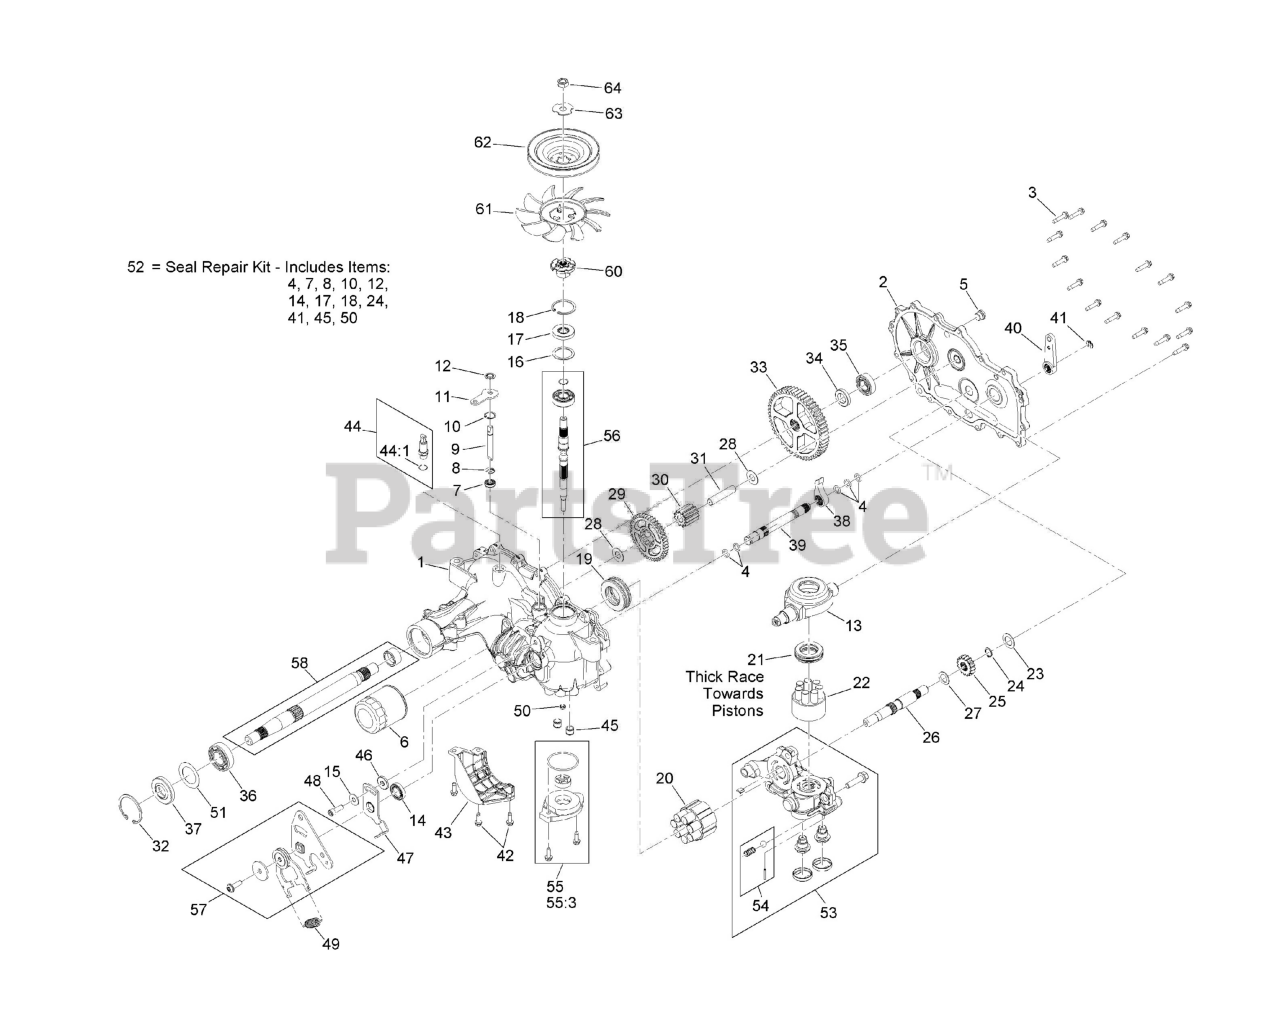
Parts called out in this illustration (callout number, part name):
1	MAIN HOUSING KIT
2	RH HOUSING SIDE KIT
3	SCREW-HHF
6	ELEMENT-OIL FILTER, HYD
7	SEAL-LIP
8	RING-RETAINING, EXTERNAL
9	ROD-BYPASS
10	RING-RETAINING, INTERNAL
11	ARM-BYPASS
12	RING-RETAINING, EXTERNAL
13	SWASHPLATE-TRUNNION
14	SEAL-LIP
17	SEAL-LIP
18	RING-RETAINING
19	BEARING-THRUST
20	MOTOR CYLINDER BLOCK KIT
21	BEARING-THRUST
22	PUMP BLOCK ASM
23	WASHER-FLAT
24	RING-RETAINING
25	GEAR-16T
26	SHAFT-MOTOR
29	GEAR-43T
30	GEAR-11T
31	PIN-JACKSHAFT
32	RING-RETAINING
33	GEAR-54T
35	BEARING-BALL
36	BEARING-BALL
38	PAWL-BRAKE
39	SHAFT-BRAKE, INBOARD
40	HANDLE-BRAKE
41	RING-RETAINING, EXT
43	GUARD-FILTER, RH
44	ADAPTER-STRAIGHT
44:1	O-RING
47	ARM-NEUTRAL, RIGHT
48	SCREW-SH
49	SPRING-EXTENSION
50	Seal-Gerotor
52	SEAL KIT
53	RH CENTER SECTION CHARGE
54	CHARGE RELIEF KIT
55	CHARGE KIT
55:3	O RING-SEAL
56	INPUT SHAFT KIT
57	CONTROL ARM KIT
58	AXLE SHAFT KIT
60	HUB-PULLEY
63	WASHER-SLOTTED
